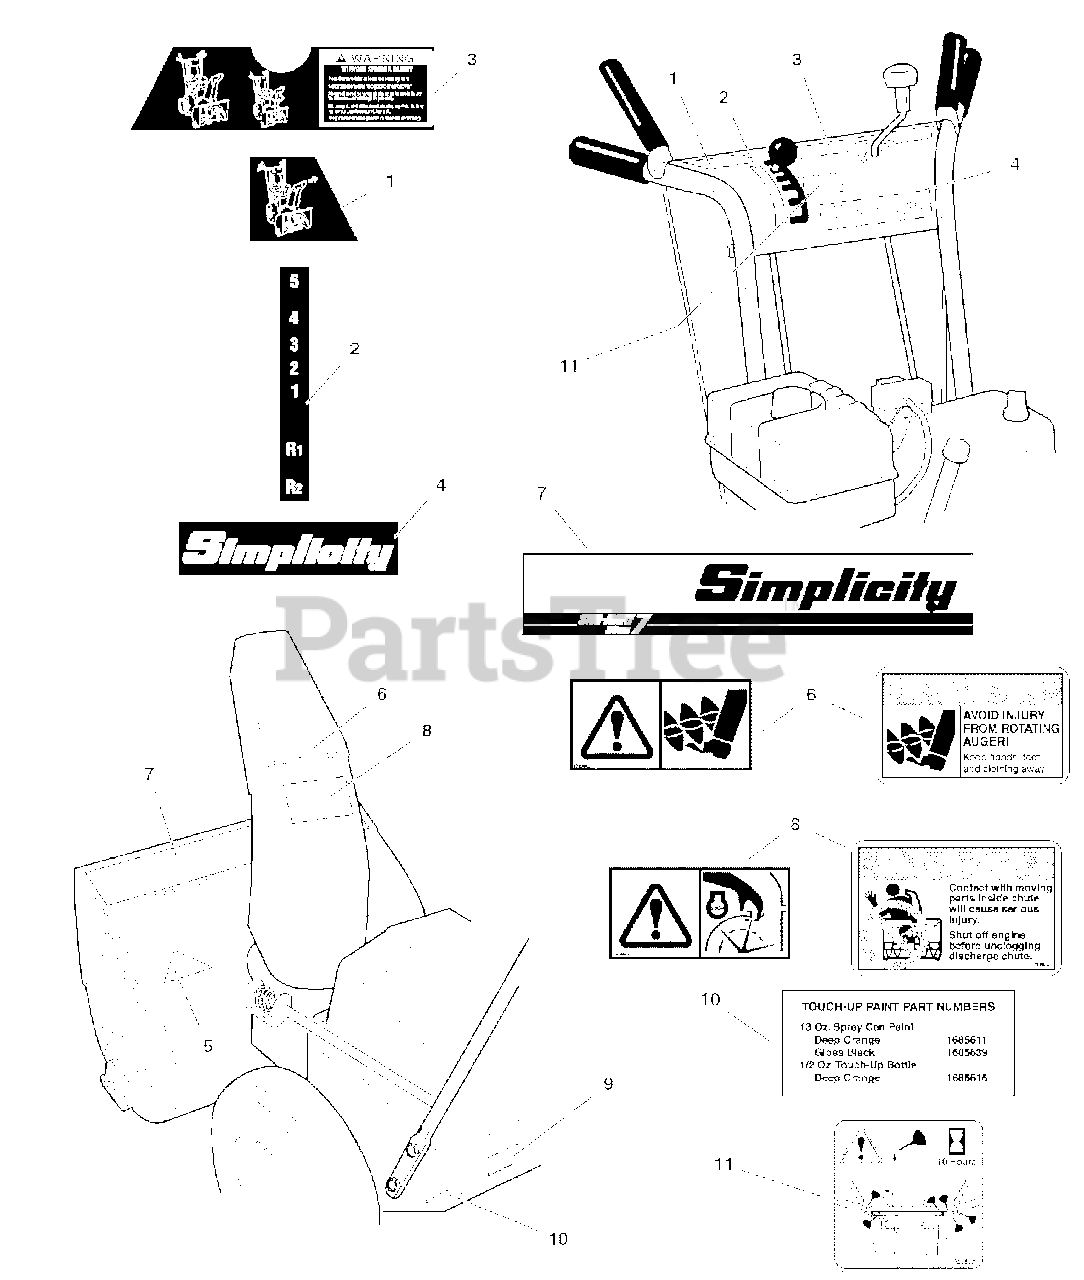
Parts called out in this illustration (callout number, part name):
1	DECAL, Auger Control
2	DECAL, Speed Selector
3	DECAL, Warning / Main Dash Panel (Export)
3	DECAL, Warning / Main Dash Panel
4	DECAL, Simplicity Logo
5	DECAL, OPEI (Not Serviced)
6	DECAL, Auger Danger
6	DECAL, Auger Danger (Export)
7	DECAL, Stripe, 960
8	DECAL, Discharge Chute Danger (Export)
8	DECAL, Discharge Chute Danger
9	I.D. Tag (Not Serviced)
10	DECAL, Touch-up Paint
11	DECAL, Handle Lubrication
13	DECAL, Hinge, Orange
